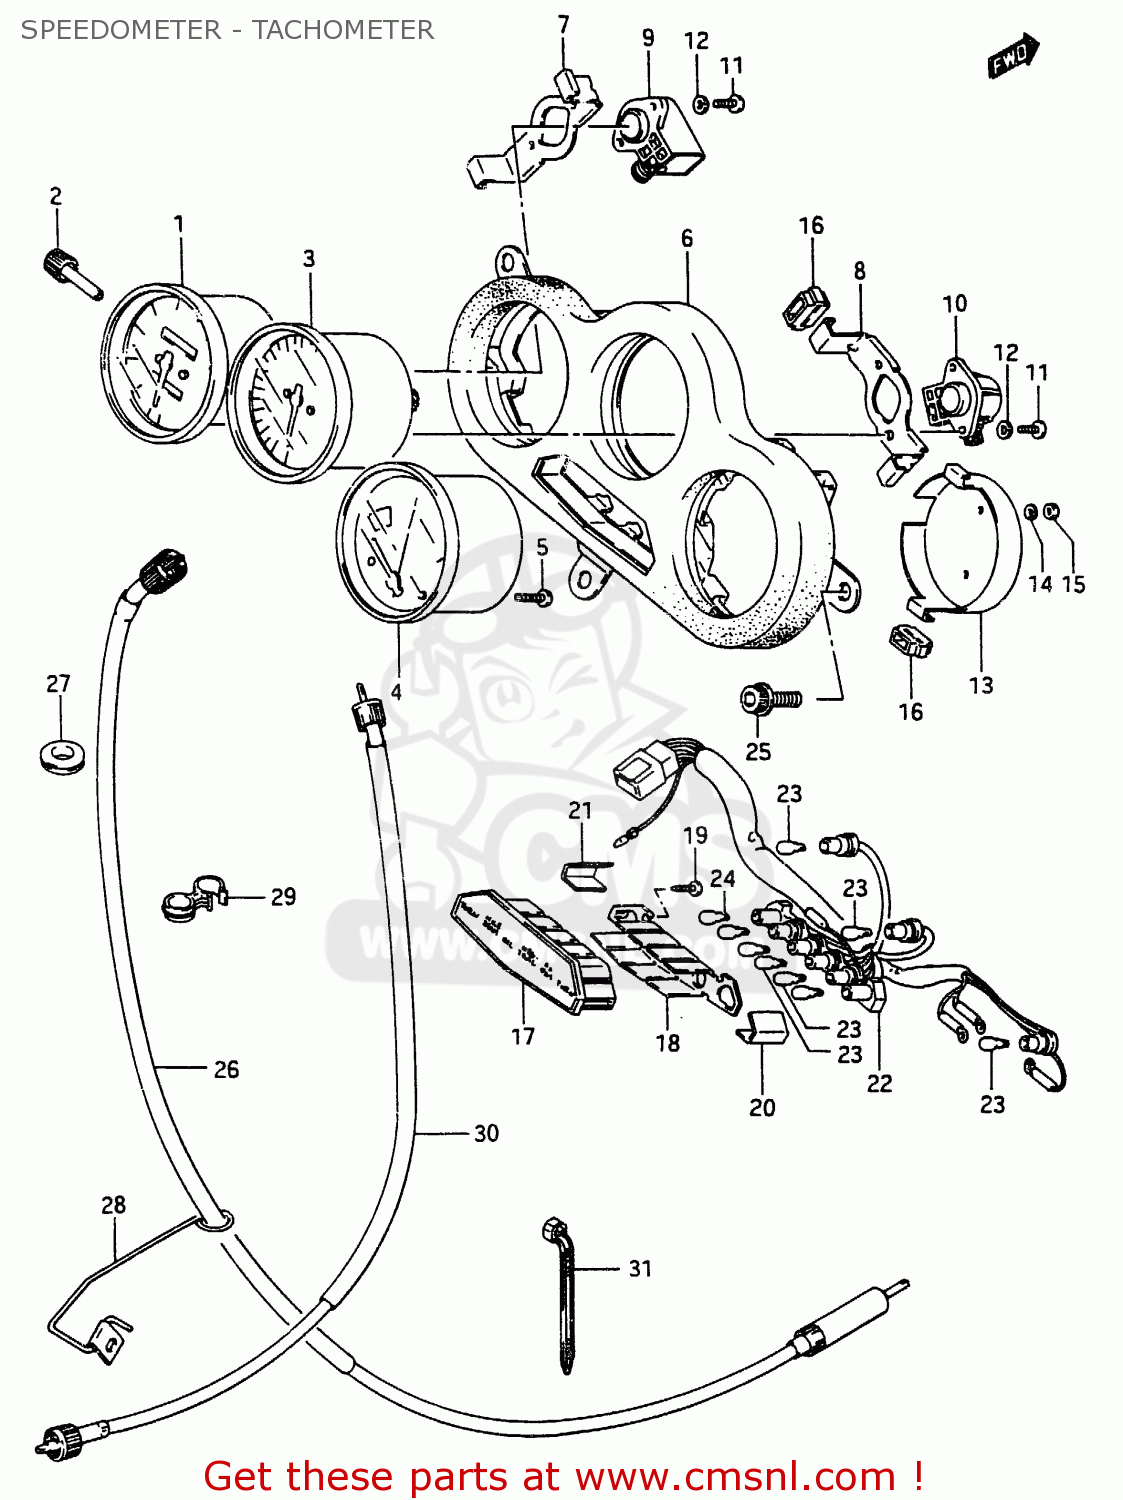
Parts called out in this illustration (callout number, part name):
1	SPEEDOMETER (KILO)
2	KNOB,TRIP
3	TACHOMETER
4	METER, TEMPERATURE
5	SCREW
6	BRACKET,METER
7	PLATE,SPEEDOMETER
8	PLATE, TACHOMETER
9	BOX,METER GEAR
10	BOX, TACHOMETER GEAR
11	SCREW
12	LOCK WASHER
13	PLATE,TEMP METER
14	WASHER
15	NUT
16	CUSHION
17	CASE, PILOT LAMP
18	PLATE,PILOT LAMP
19	SCREW
20	PLATE,TURN,R
21	PLATE,TURN,L
22	SOCKET, METER
23	BULB(12V3W,WB371,T7)
24	BULB(12V1.7W,WB372,T7)
25	BOLT
26	CABLE ASSY,SPEEDOMETER
27	GROMMET
28	GUIDE, SPEEDOMETER CABLE
29	GUIDE,SPEEDOMETER CABLE
30	CABLE ASSY,TACHOMETER
31	CLAMP(L:165)
